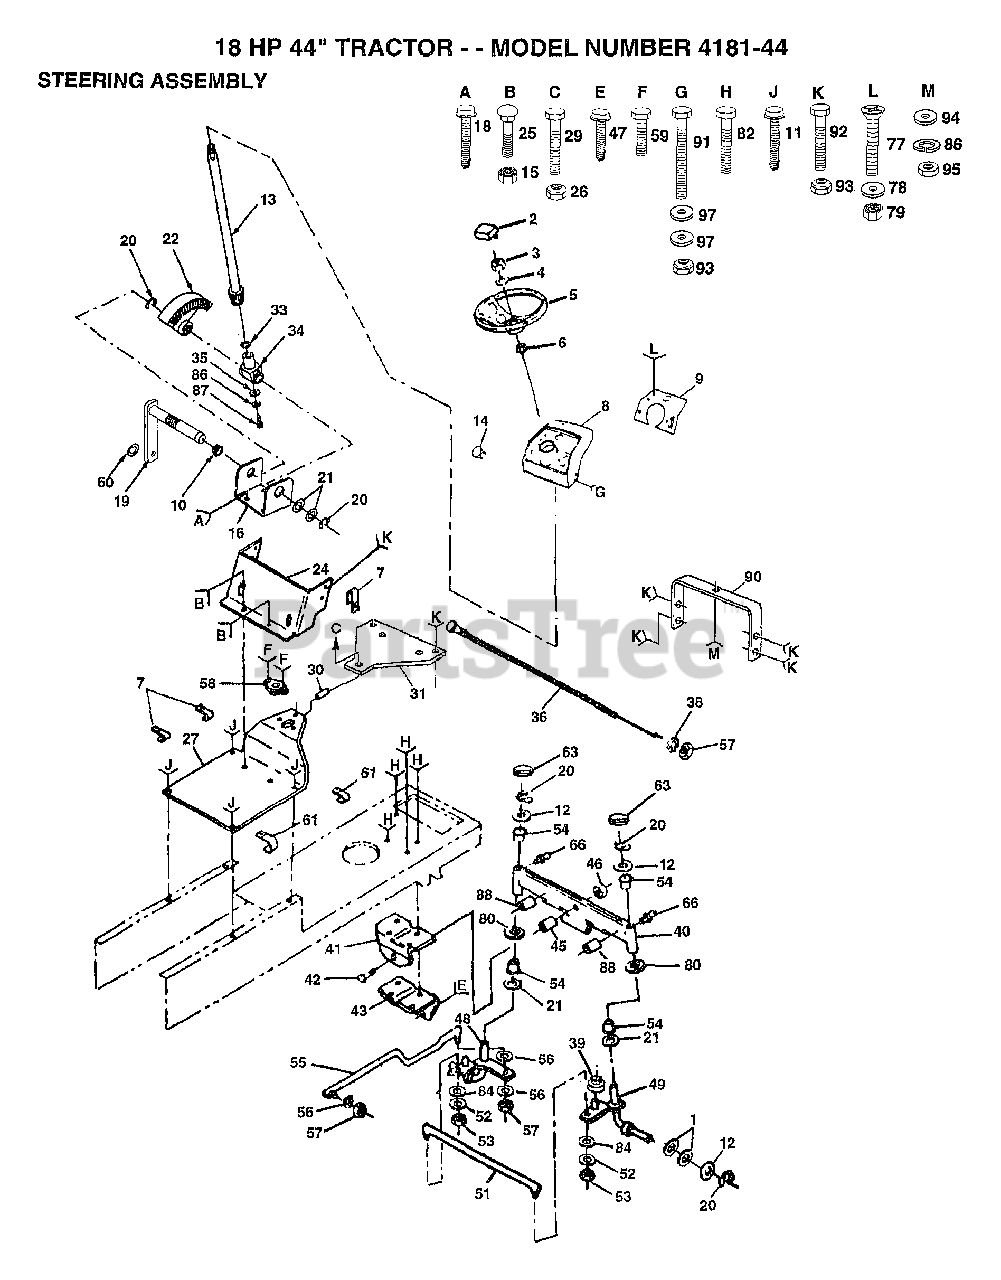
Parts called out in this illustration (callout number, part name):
1	WASHER
2	"INSERT,STR WHEEL"
4	WASHER
6	ADAPTER LT
7	CLIP T
8	DASHBOARD BLACK
9	PLATE SLKSCR YP
10	NYLINER T
11	SCREW
12	WASHER
14	PLUG-DASH T
16	"BRKT,STEERING"
18	SCREW
20	RING
21	WASHER .T
22	GEAR SECTOR
24	LOWER DASH
25	SCREW
26	NUT
29	BOLT
30	SPACER
31	PLATE.SUPT.BATTER
33	THRUST WASHER
34	SUPPORT.SHAFT
36	CHOKE CONTROL
38	LOCKWASHER
39	BUSHING SPIN STOP
40	AXLE ASM FRONT
41	SUPPORT-SADDL T
42	BOLT LT
43	SUPPORT.SADDLE.FT
45	BEARING
46	"NUT-LOC,FLANGE LT"
47	SCREW LT
51	TIE ROD
52	LOCKWASHER
53	NUT.LOCK.5/16-24
54	COL. SRTG. BEAR.
56	LOCKWASHER
60	WASHER
61	"CLIP,INSULATOR"
63	CAP
66	ZERK M
77	SCREW
78	WASHER
80	WASHER
82	SCREW
84	WASHER M
86	LOCKWASHER
87	"SCREW,SPECIAL"
88	AXLE PIN
90	SUPPORT ASS'Y
91	BOLT
92	BOLT
93	NUT
94	WASHER PM
97	WASHER
